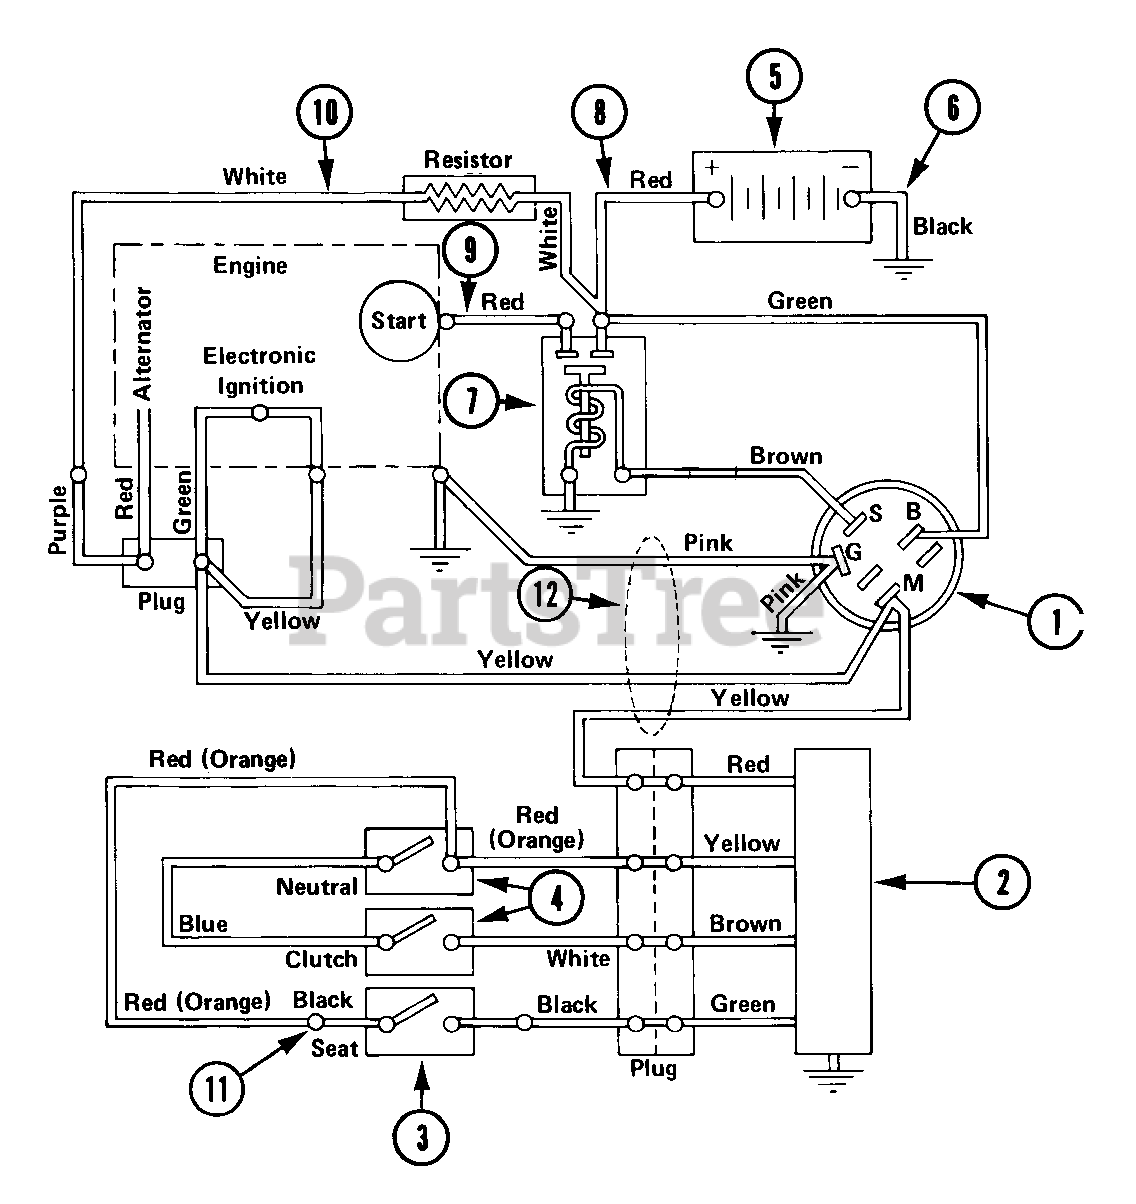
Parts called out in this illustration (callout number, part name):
1	IGNITION SWITCH ASSEMBLY
2	MODULE
3	SAFETY SWITCH
3	SEAT WITH SWITCH REPLACEMENT P
3	SWITCH SEAT
4	SWITCH INTERLOCK
5	BATTERY
6	GROUND CABLE .25X13.00X.31
7	SOLENOID
8	STARTER CABLE 16"
9	STARTER CABLE 13"
10	CHARGING WIRE
11	ADAPTER - SEAT SWITCH
12	WIRE HARNESS
14	REGULATOR
